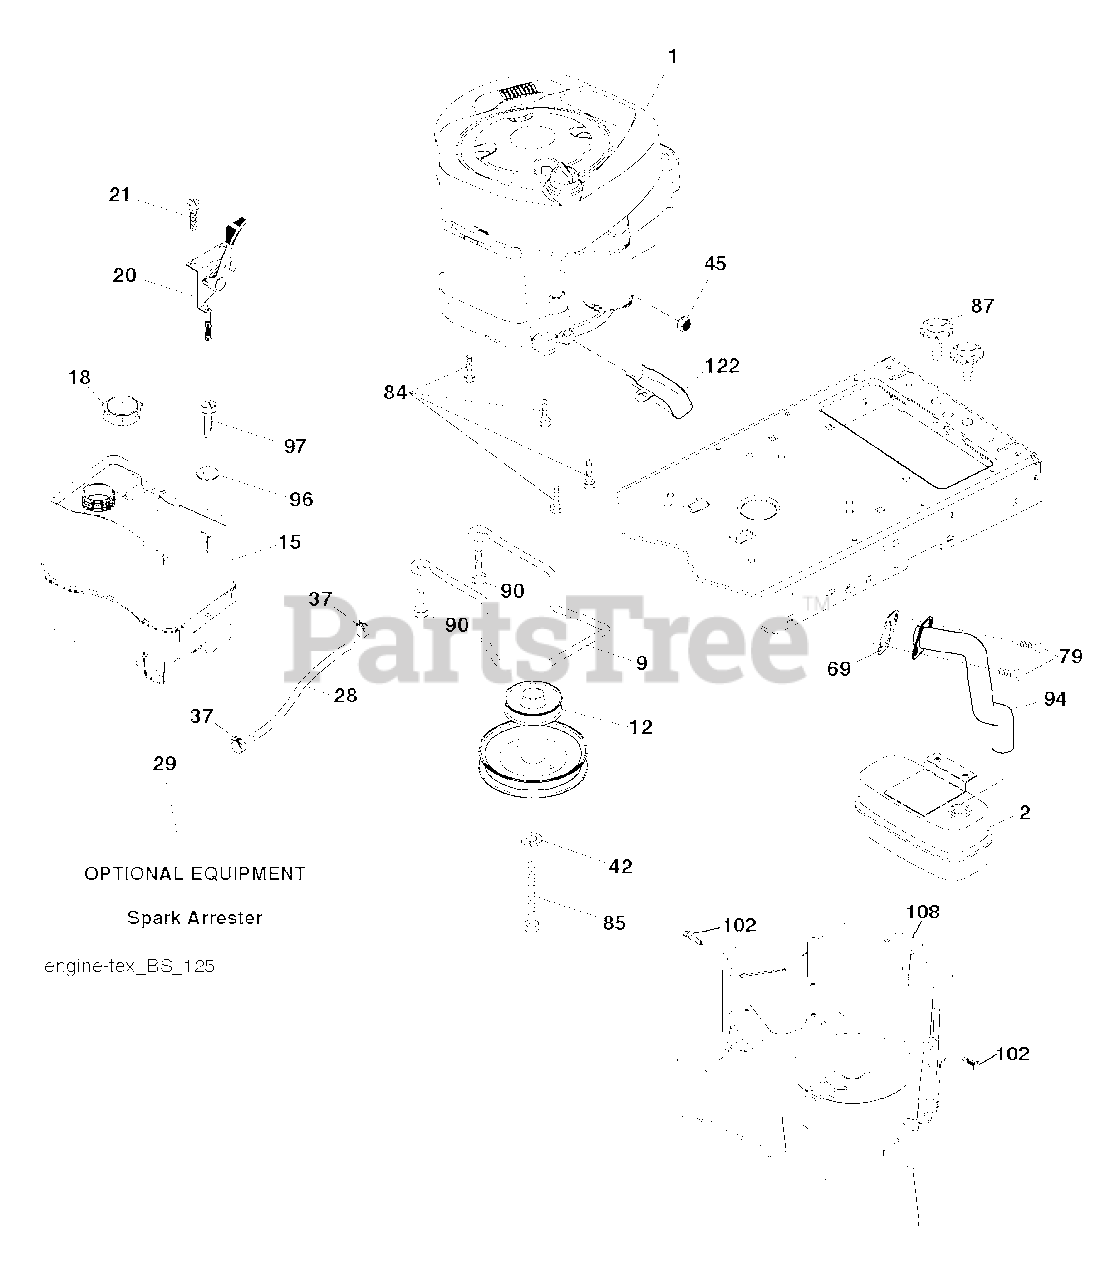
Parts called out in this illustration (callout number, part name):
2	MUFFLER.ASM.SNGL.XTNDED.DFLCTR
9	KEEPER.BELT.ENG.4.25"2.BLT.431
12	ENGINE.PULLEY
15	FUEL.TANK.ASM.NON-EPA
18	CAP ASM.FUEL.2.25"FR.
20	THROTTLE.COBRA.21".RSTART.BLK
21	SCREW.#10 X 0.750.BOS
28	LINE.FUEL.20
29	KIT.SPARK ARRESTOR 794945 B&S
37	HOSE CLAMP
42	LOCKWASHER
45	NUT
69	REPL BY 532 27 22-93
79	SCREW.SOCKET HD.5/16-1
84	SCREW.3/8-16
85	BOLT.HEX.7/16-20X4.GR5.1.5BLUE
87	BOLT, 5/16-18 X 1 3/4
90	SCREW 3/8-16X1
94	EXHAUST.TUBE.B&S.28/31
97	SCREW HEXWSHR 1/4-20X3/4
102	SCREW 5/16-18X1
108	COVER PULLEY
122	EXTENSION DRAIN OIL
